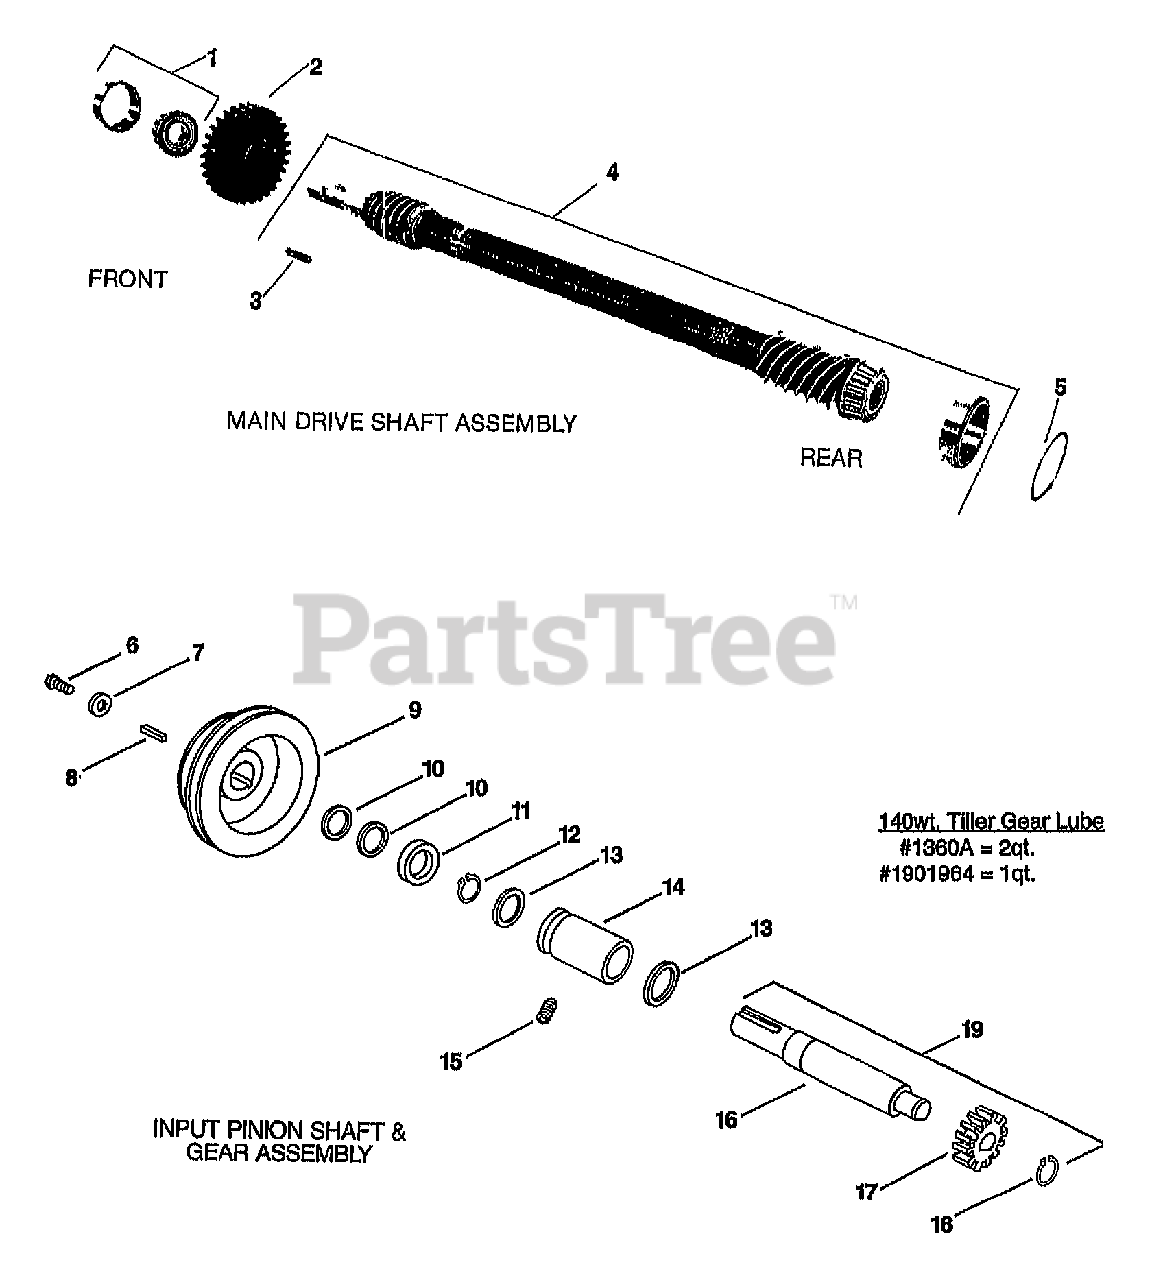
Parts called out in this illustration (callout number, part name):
1	KIT-BRG CONE&RACE-DRIVESHAFT
2	GEAR-SPUR 30 TEETH
3	KEY-.188 SQX1.0
4	KIT-DRIVESHAFT
5	SHIM-1.75X1.5X.01
5	SHIM-1.75X1.5X.03
5	SHIM-1.75X1.5X.005
6	SCR-HH 5/16-24X.75 G5 ZP
7	WASHER-.827X.331X.098
8	KEY-.188 SQX1.0
9	PULLEY-TRANS MACH
10	WASHER # .875 X .65 X .06
11	SEAL-PINION SHAFT PT/85030/00
12	RING-RETAIN EXT .707 ID (SNAP RING)
13	WASHER-1.022X.752X .059
14	BUSHING-1.24X.75X1.8 GRVD
15	SCR-SS 5/16-18X.375
16	SHAFT-PINION(P-V)
17	GEAR-PINION P/M
18	RING-BOWED EXT .461 ID (SNAP RING)
19	PINION W/GEAR&SNAP RING (INCL. #20791, #20792, & #9093)
